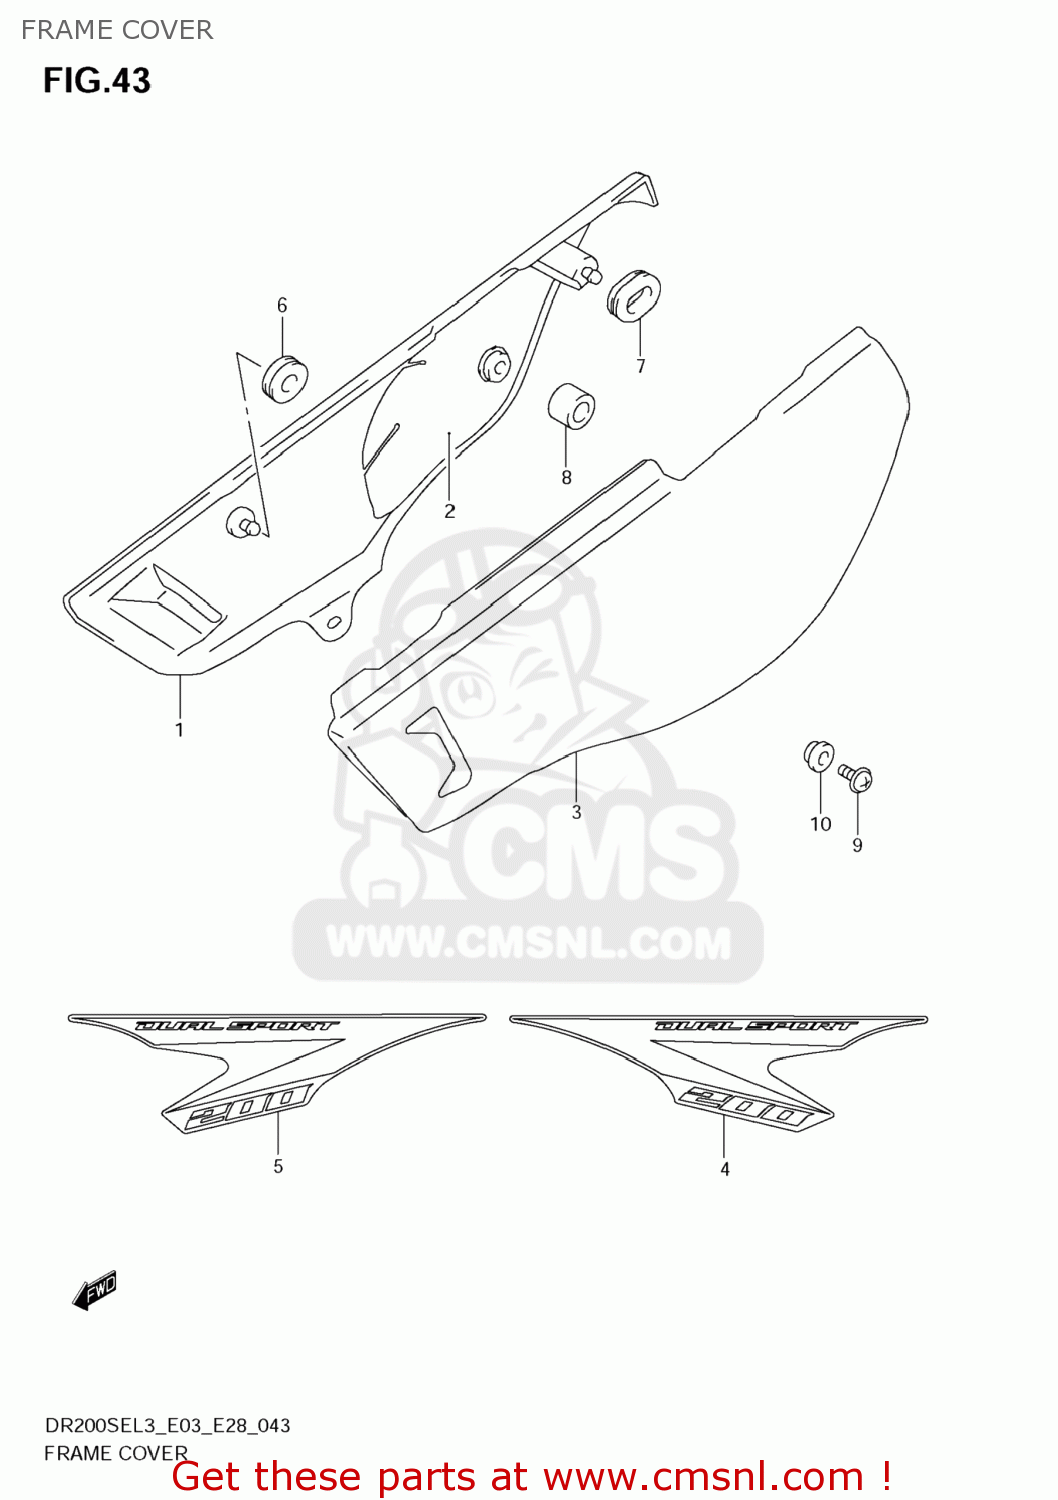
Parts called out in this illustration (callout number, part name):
1	COVER,FRAME,R(BLACK)
2	SHIELD,FRAME COVER,R
3	COVER,FRAME,L(BLACK)
4	TAPE,FRAME COVER,R
5	TAPE,FRAME COVER,L
6	CUSHION
7	CUSHION
8	CUSHION
9	SCREW(6X16)
10	WASHER
